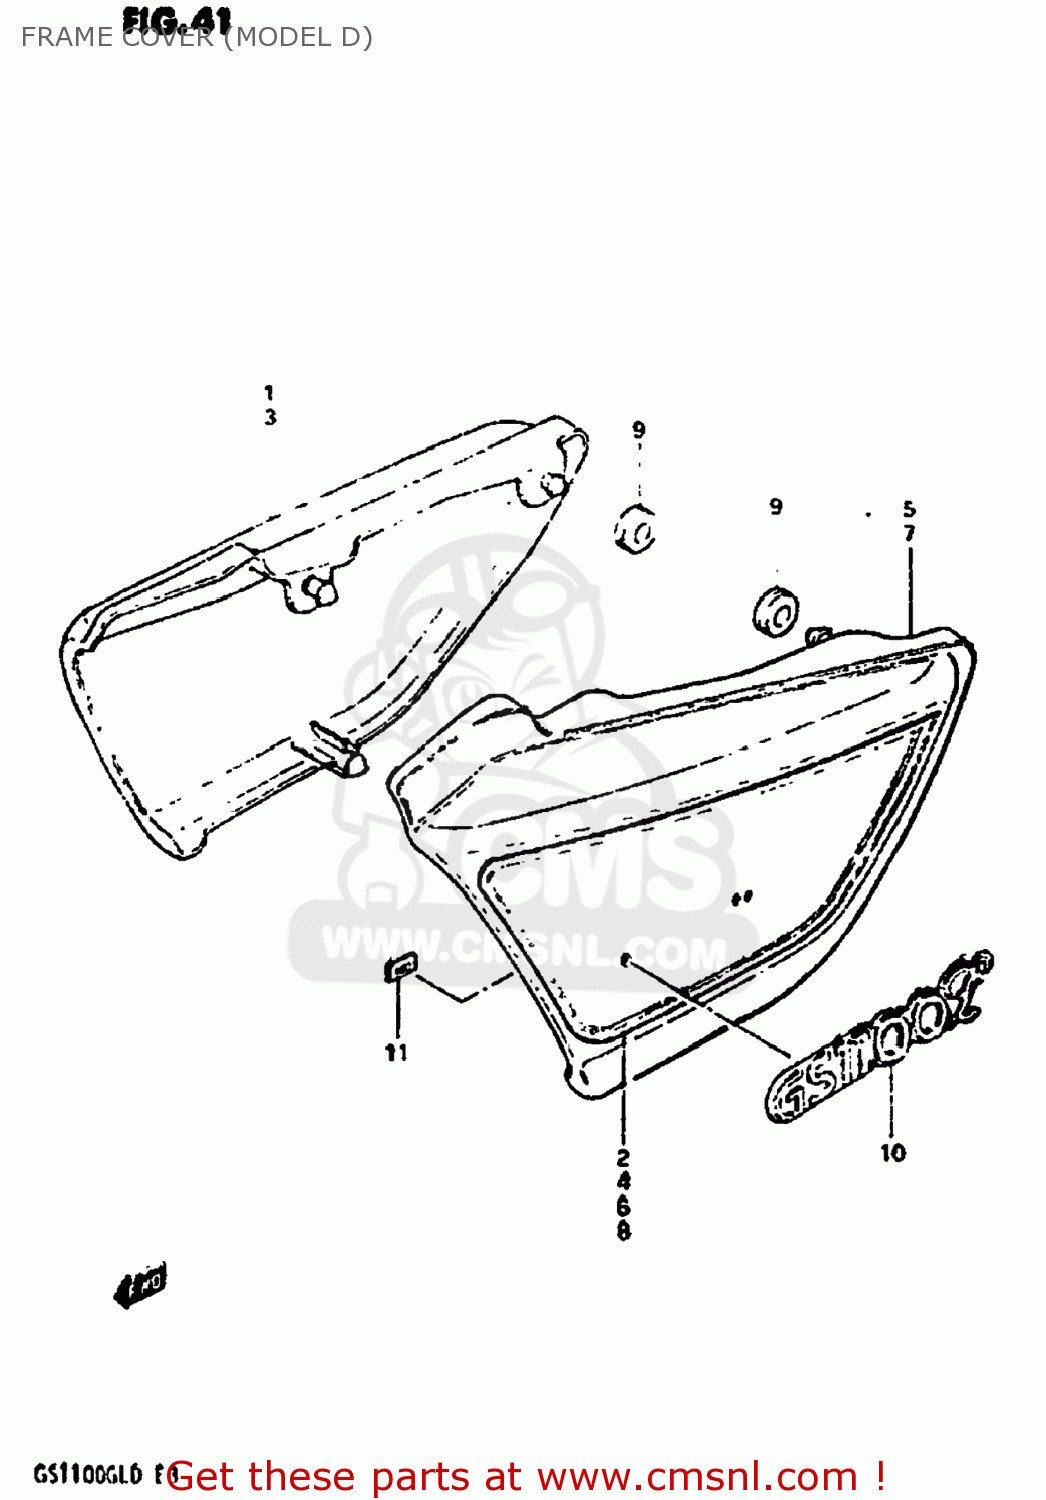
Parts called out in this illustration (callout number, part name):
1	COVER,FRAME,RIGHT
2	TAPE SET,FRAME COVER
3	COVER,FRAME,RIGHT
4	TAPE SET,FRAME COVER
5	COVER,FRAME,LEFT
6	TAPE SET,FRAME COVER,LEFT
7	COVER,FRAME,LEFT
8	TAPE SET,FRAME COVER
9	CUSHION
10	EMBLEM,FRAME COVER
11	NUT
